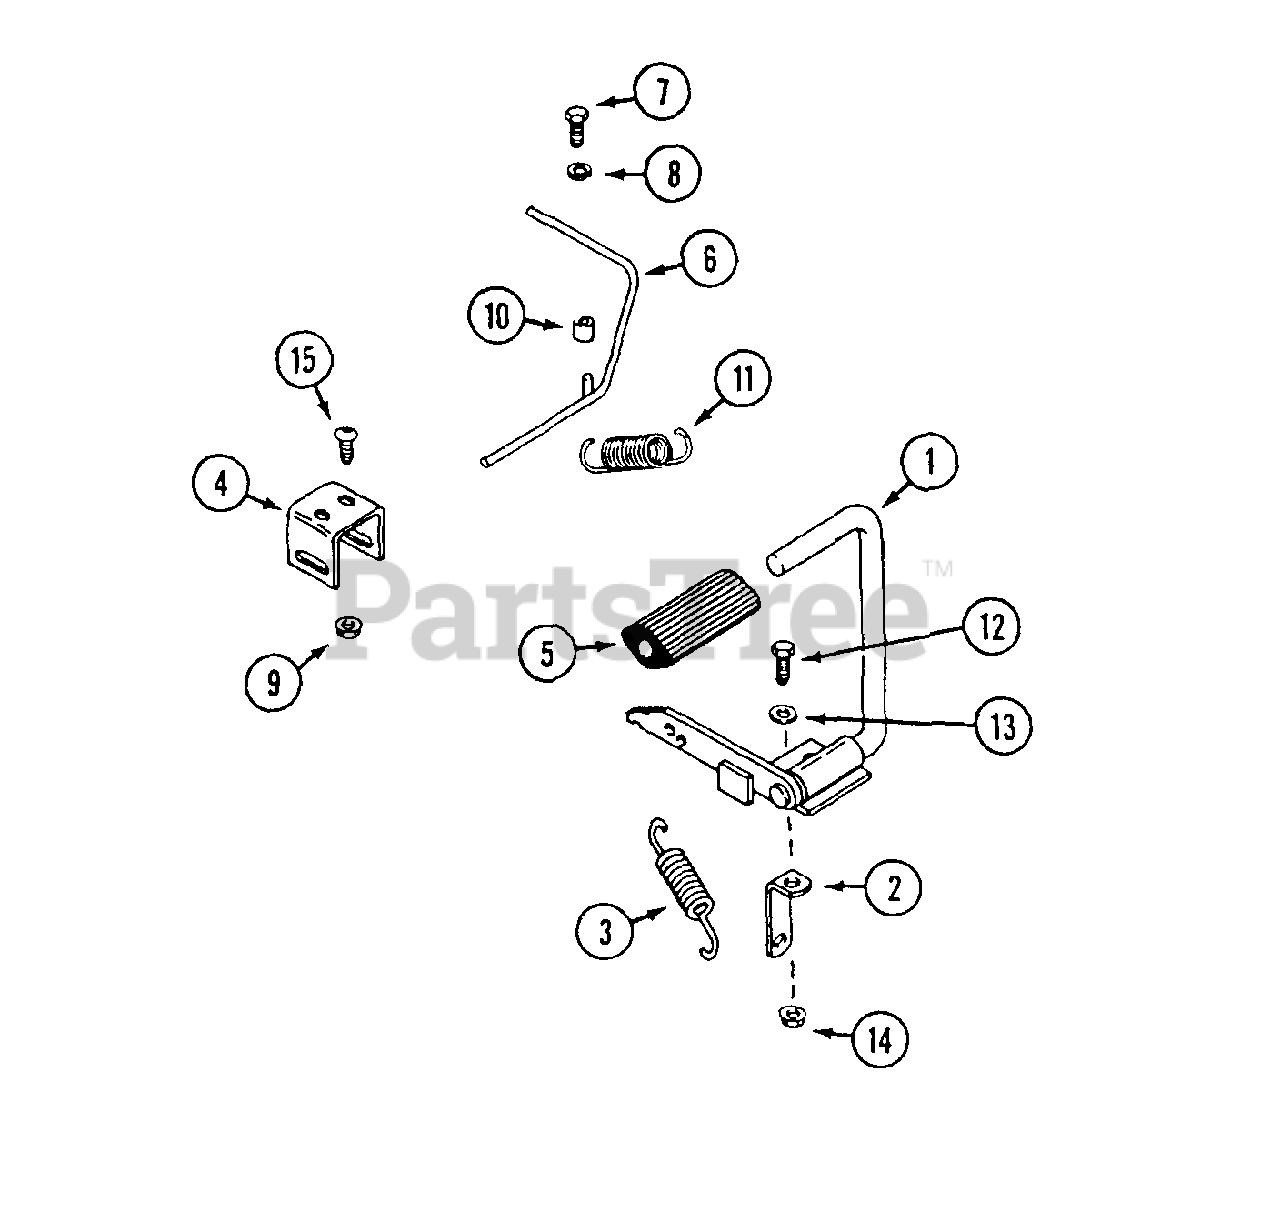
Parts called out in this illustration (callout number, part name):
1	PEDAL - parking brake
2	TAB - spring mount
3	SPRING - brake return
4	BRACKET - brack lock
5	PAD - brake pedal
6	LEVER - brake lock
7	SCREW - 5/16" - 18 x 5/8" allen head
8	LOCKWASHER - 5/16"
9	NUT - 1/4" - 20 flange lock
11	SPRING - return, lock lever
12	BOLT - 5/16" - 18 x 1"
13	WASHER - 5/16"
14	NUT - 5/16" - 18 flange lock
15	SCREW - 1/4" - 20 x 1/2" allen head
